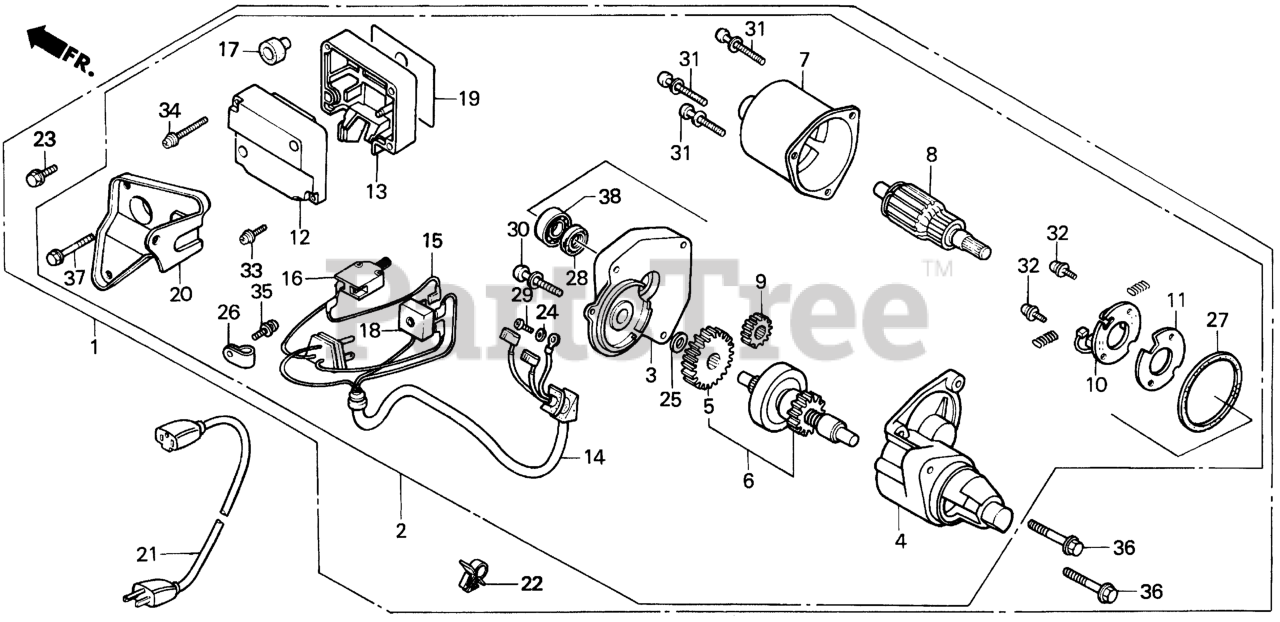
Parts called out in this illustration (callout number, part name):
2	MOTOR ASSY., STARTER (A.C.) Use up to Engine SN 1171448.
3	HOUSING, CENTER Use up to Engine SN 1171448.
4	HOUSING, PINION Use up to Engine SN 1171448.
5	GEAR, REDUCTION Use up to Engine SN 2056819.
6	CLUTCH, OVERRUNNING Use up to Engine SN 1171448.
7	YOKE Use up to Engine SN 2056819.
8	ARMATURE Use up to Engine SN 1171448.
9	GEAR, DRIVE Use up to Engine SN 2056819.
10	HOLDER ASSY., BRUSH Use up to Engine SN 2056819.
11	SHEET, HOLDER Use up to Engine SN 2056819.
12	COVER Use up to Engine SN 2056819.
13	CASE Use up to Engine SN 2056819.
14	WIRE Use up to Engine SN 2056819.
15	SUB-WIRE Use up to Engine SN 2056819.
16	SWITCH, STARTER (Honda Code 2299584). (A.C. 380V-16A)
17	CAP Use up to Engine SN 2056819.
18	DIODE Use up to Engine SN 1171448.
19	PLATE, CAUTION Use up to Engine SN 2056819.
20	BRACKET, SWITCH BOX Use up to Engine SN 1171448.
21	WIRE, POWER Use up to Engine SN 2056819.
22	CLIP B, CABLE
23	BOLT, FLANGE (6X12) (CT200)
24	WASHER, STAR (4MM) Use up to Engine SN 2056819.
25	WASHER Use up to Engine SN 2056819.
26	CLIP, CORD (5/16) Use up to Engine SN 2056819.
27	GASKET Use up to Engine SN 2056819.
28	OIL SEAL Use up to Engine SN 2056819.
29	SCREW, PAN (4X6) Use up to Engine SN 2056819.
30	SCREW-WASHER (5X16) Use up to Engine SN 2056819.
31	SCREW-WASHER (5X30) Use up to Engine SN 2056819.
32	SCREW-WASHER (4X12) Use up to Engine SN 2056819.
33	SCREW-WASHER (4X25) (NOT AVAILABLE)
34	SCREW-WASHER (4X30)
35	SCREW-WASHER (5X16) Use up to Engine SN 2056819.
36	BOLT, FLANGE (8X40) Use up to Engine SN 1003236.
37	BOLT, FLANGE (6X40)
38	BEARING, RADIAL BALL Use up to Engine SN 2056819.
